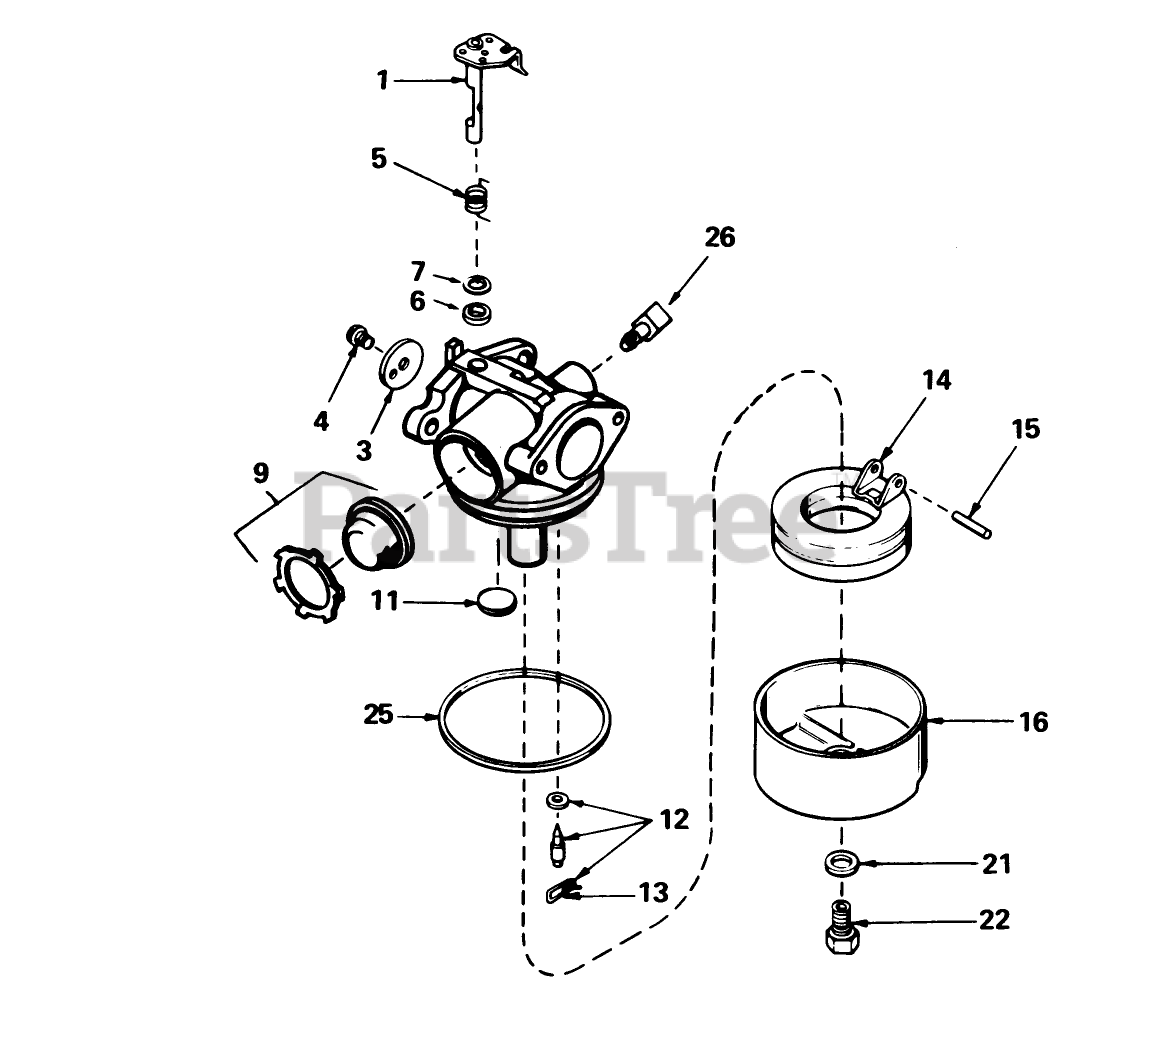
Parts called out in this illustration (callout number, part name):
1	Throttle Shaft and Lever ASM
3	Throttle-Shutter
4	Screw-Shutter
5	Spring-Return, Throttle
6	Seal-Dust
7	Washer-Seal, Dust
9	Primer Assy.
11	Plug-Welch, Atmospheric Vent
12	Inlet Needle, Seat Clip Assy. (Incl. No. 3)
13	Clip-Spring
14	Float
15	Shaft-Float
16	Bowl Float
21	Gasket-Bowl
22	Nut-Float Bowl
25	O Ring-Bowl, Float
26	Fitting-Fuel
